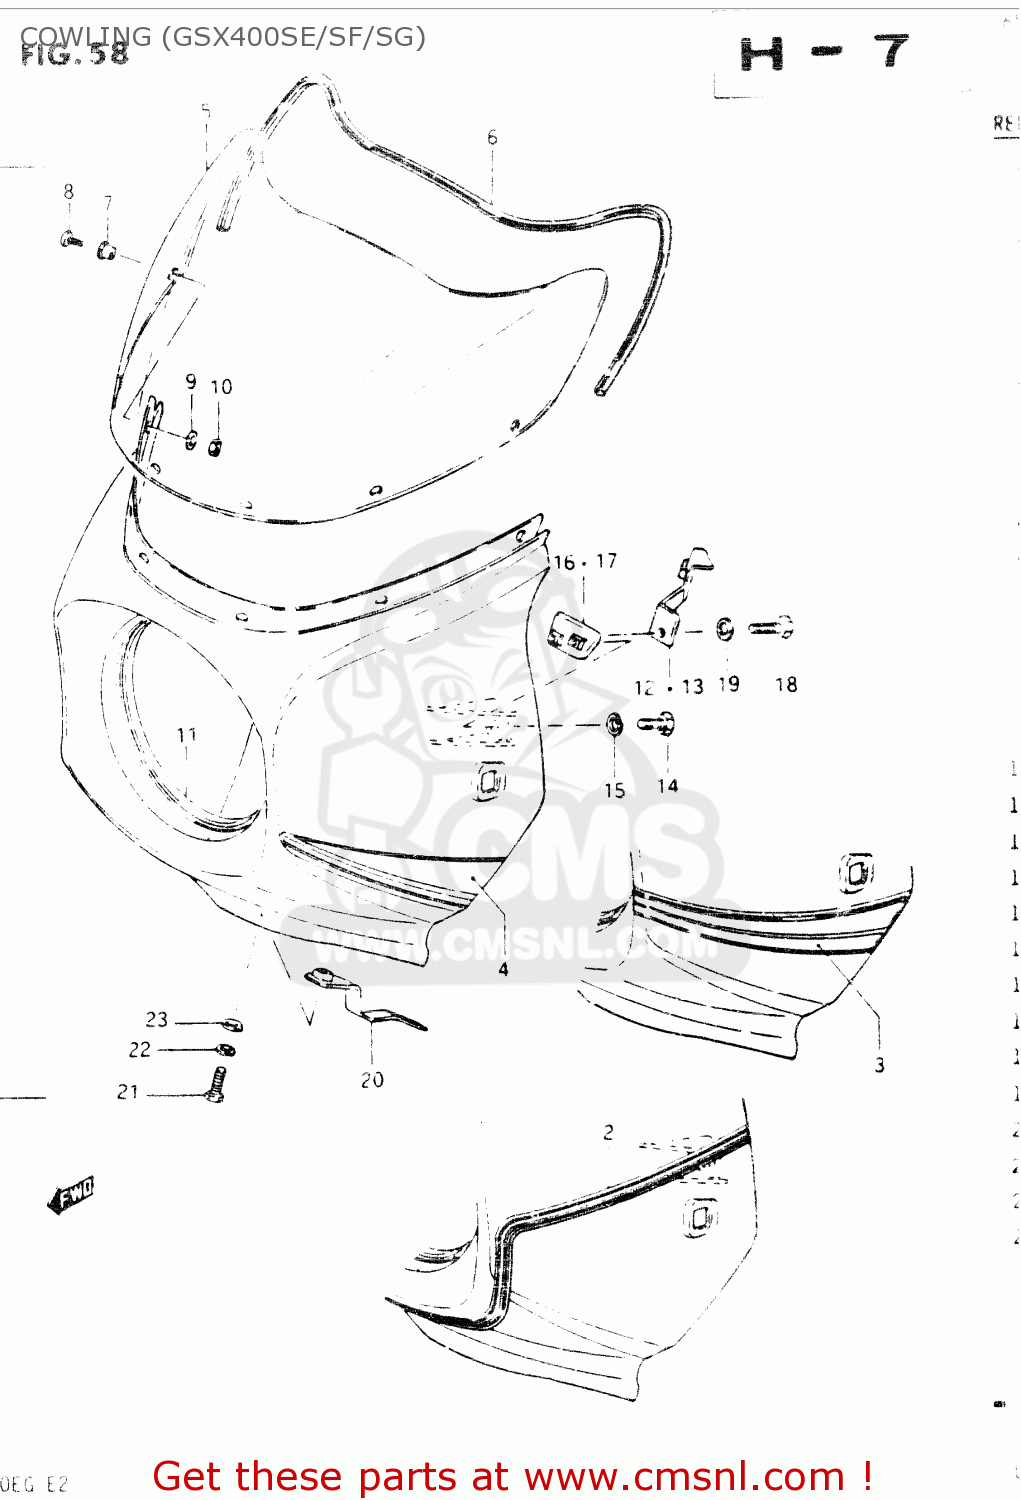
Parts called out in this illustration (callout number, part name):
1	COWLING ASSY (WHITE/RED)
2	TAPE SET
3	TAPE SET
4	TAPE SET
5	WINDOW
6	MOULDING
7	CUSHION
8	SCREW
9	WASHER,5MM
10	NUT 8MM
11	MOLDING,HEADLAMP GRILL
12	BRACKET,COWLING RH
13	BRACKET,COWLING LH
14	BOLT
15	WASHER,LOCK
16	BRACKET, FITTING RH
17	BRACKET, FITTING LH
18	BOLT 6X16
19	WASHER (6.5X18X1.6)
20	BRACKET, LOWER
21	BOLT
22	WASHER,LOCK
23	WASHER
